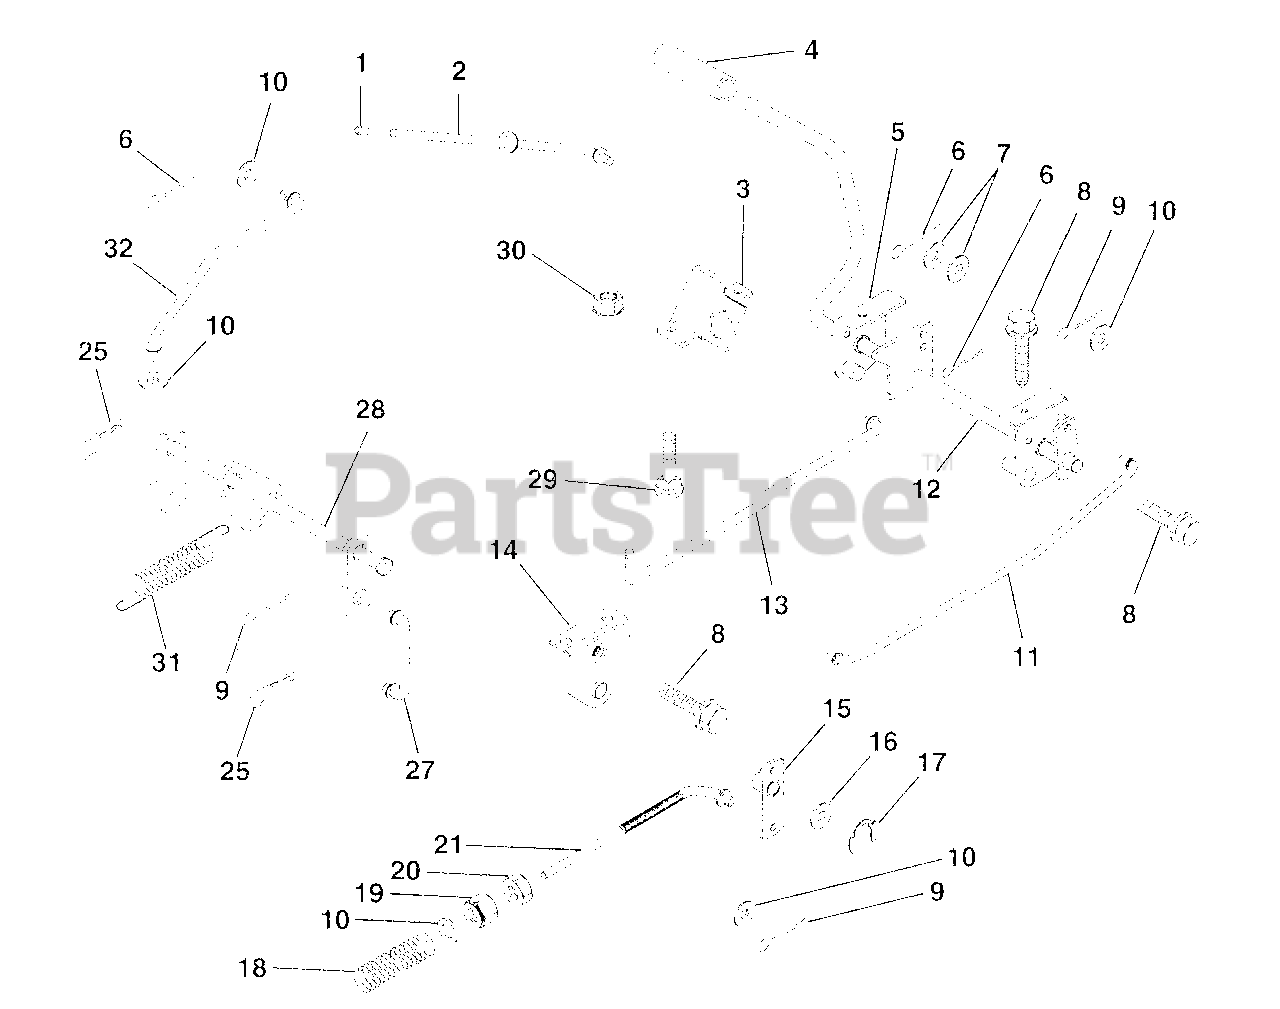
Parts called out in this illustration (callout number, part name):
1	Cap, Plunger
2	Rod, Parking Brake
3	Bracket, Parking Brake
4	Cover, Pedal
5	Bracket, Clutch/Brake Pedal, L.H.
6	Pin, Cotter 3/32 x 3/4
7	Washer 13/32 x 5/8 x 16 Gauge
8	Screw, Hex Head, Thd., Roll. 5/16-18 x 1/2
9	Pin, Cotter 1/8 x 3/4
10	Washer 13/32 x 13/16 x 16 Gauge
11	Rod, Brake, Front
12	Assembly, Clutch/Brake Pedal
13	Rod, Clutch
14	Bracket, Lift Shaft
15	Assembly, Brake, Pivot, Arm
16	Washer 25/32 x 1-1/8 x 16 Gauge
17	Ring, Klip
18	Spring, Brake Rod
19	Nut, Hex, Jam 3/8-16 UNC
20	Locknut, Hex, with Washer Insert 3/8-16 UNC
21	Rod, Brake, near
22	Trunnion, Lift
23	Nut, Crownlock 3/8-16 UNC
24	Washer 13/32 x 1-1/4 x 12 Gauge
25	Spring, Retainer
26	Nut, Centerlock 3/8-16 UNC
27	Link, Lift, Rear
28	Assembly, Rear Mower Lift
29	Bolt, Carriage 5/16-18 UNC x 3/4
30	Nut, Hex, Keps 5/16-16 UNC
31	Spring, Counterbalance
32	Link, Lift Lever
